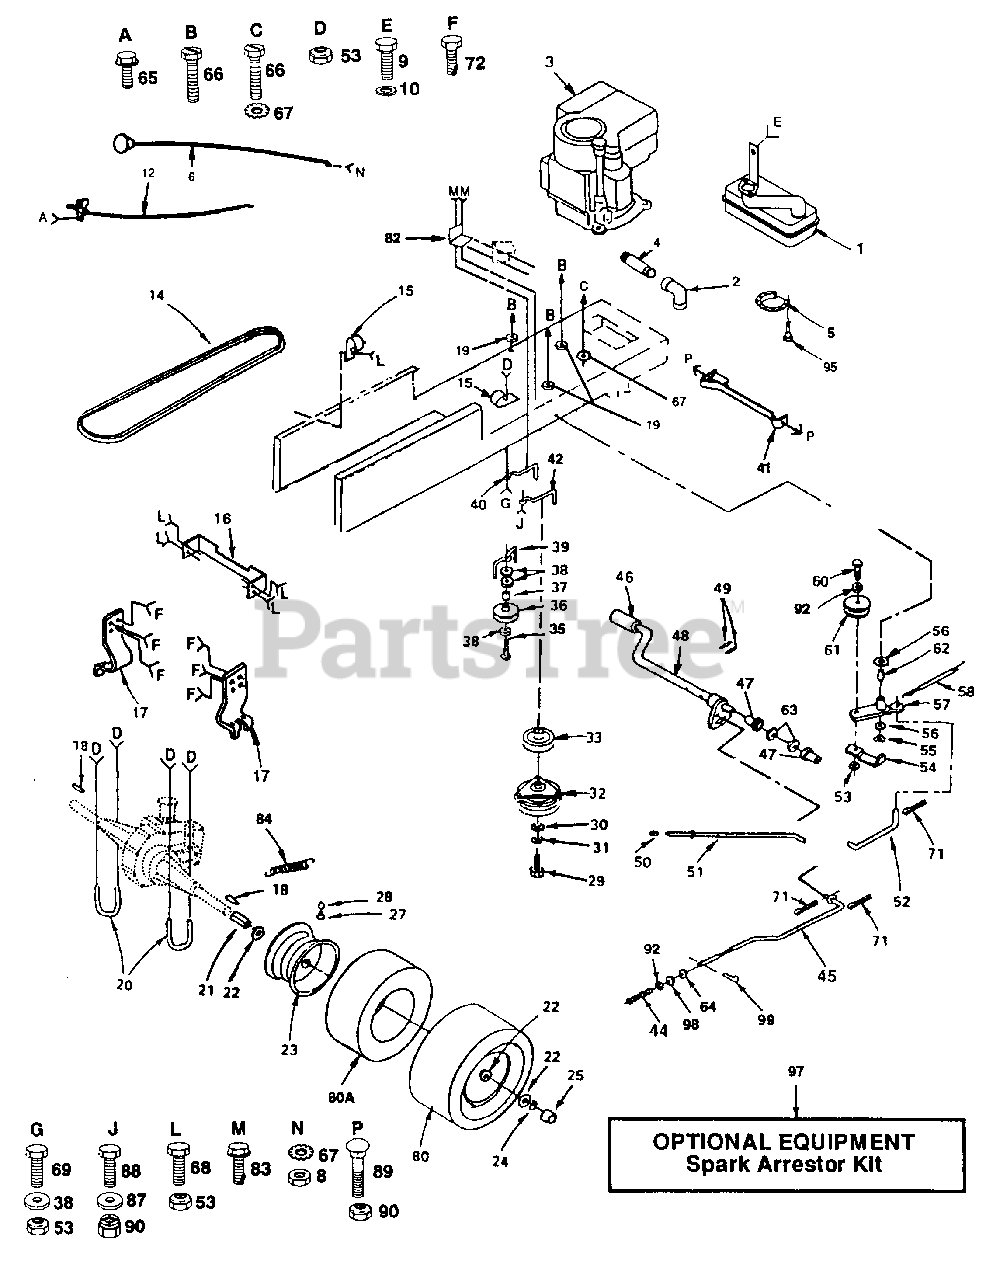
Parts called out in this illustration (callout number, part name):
1	Muffler (AYP part number)
2	Elbow, STD 90 3/8-18NPT (AYP part number)
4	Nipple, Pipe (AYP part number)
5	Deflector, Exhaust (AYP part number)
6	Control, Choke (AYP part number)
8	Nut, Fin Hex 3/8-24 UNF (AYP part number)
9	Bolt, Hex HD 5/16-18 UNC X 1/2 (AYP part number)
10	Washer, Lock Hvy. Helical Spring (AYP part number)
12	Control, Throttle (AYP part number)
14	V-Belt, Drive (AYP part number)
15	Clip (AYP part number)
16	Bracket, Mounting, Hydro T/A (AYP part number)
17	Bracket, Transaxle (AYP part number)
18	Key, Square 1/4 x 2 (AYP part number)
19	Washer, Lock, Hvy. Hel. Spring (AYP part number)
20	U-Bolt, 3/8-16 x 2-3/4 (AYP part number)
21	Spacer, Split (AYP part number)
22	Washer, 1-1/32 x 1-5/8 x 16 Ga, (AYP part number)
23	Rim, Rear (AYP part number)
24	E-Ring (AYP part number)
25	Cap, Axle (AYP part number)
27	Stem, Valve (AYP part number)
28	Cap, Valve (AYP part number)
29	Bolt, Fin M10 X 1.5 X 100 mm (AYP part number)
30	Washer, 1-1/2 OD X 15/32 ID X .250 (AYP part number)
31	Washer, Lock 7/16 (AYP part number)
32	Clutch, Electric (AYP part number)
33	Pulley, Engine (AYP part number)
35	Bolt, Hex 3/8-16 x 2-3/4 (AYP part number)
36	Idler, Flat (AYP part number)
37	Spacer (AYP part number)
38	Washer, 13/32 x 13/16 x 12 Ga. (AYP part number)
39	Keeper, Belt (AYP part number)
40	Keeper, Belt, Engine, L.H. (AYP part number)
41	Clutch Retainer Assembly (AYP part number)
42	Belt, Keeper, Engine, R.H. (AYP part number)
44	Spring, Rod, Brake (AYP part number)
45	Rod, Brake (AYP part number)
46	Cover, Pedal (AYP part number)
47	Bearing, Nylon (AYP part number)
48	Shaft, Foot Pedal, Asm. (AYP part number)
49	Pin, Roll, 3/16 x 1 (AYP part number)
50	Cap, Plunger (AYP part number)
51	Rod, Brake, Park (AYP part number)
52	Link, Clutch (AYP part number)
53	Locknut, 3/8-16
54	Retainer, Belt (AYP part number)
55	Klip Ring (AYP part number)
56	Washer, Hardened (AYP part number)
57	Arm, Asm, Idler (AYP part number)
58	Spring, Return, Clutch (AYP part number)
60	Bolt, Hex, 3/8-16 x 1-1/2 (AYP part number)
61	Idler, V. Grove (AYP part number)
62	Bearing (AYP part number)
63	Washer, 21/32 x 1 x 16 Ga. (AYP part number)
64	Nut (AYP part number)
65	Screw, Hex Thread Cut 1/4-20 x 5/8 (AYP part number)
66	Screw, M8 X 1.25 X 25mm
67	Washer, Lock Ext Tooth 3/8 (AYP part number)
68	Bolt, Hex 3/8-16 x 3/4 (AYP part number)
69	Bolt, Hex 3/8-16 x 1 (AYP part number)
71	Pin, Cotter, 1/8 x 3/4 (AYP part number)
72	Screw, Hex, Thdrol 3/8-16 X 3/4 (AYP part number)
80	Tire (AYP part number)
80A	Tube (AYP part number)
82	Bracket, Switch (AYP part number)
83	Screw, Tap. Hex Hd, #10-24 x 1/2 Type T (AYP part number)
84	Spring, Brake Return (AYP part number)
87	Washer, 11/32 X 3/4 X 12 Ga. (AYP part number)
88	Bolt, Hex Hd. 5/16-18 X 1 (AYP part number)
89	Bolt, Carriage 5/16-18 x 3/4
90	Locknut 5/16- 18
92	Washer, 13/32 X 13/16 X 16 Ga. (AYP part number)
95	Screw. Spider Lock #8 x 1/2 (AYP part number)
97	Spark Arrestor (AYP part number)
98	Nut, Hex Jam 3/8 X 16 UNC (AYP part number)
99	Clip, Hairpin (AYP part number)
